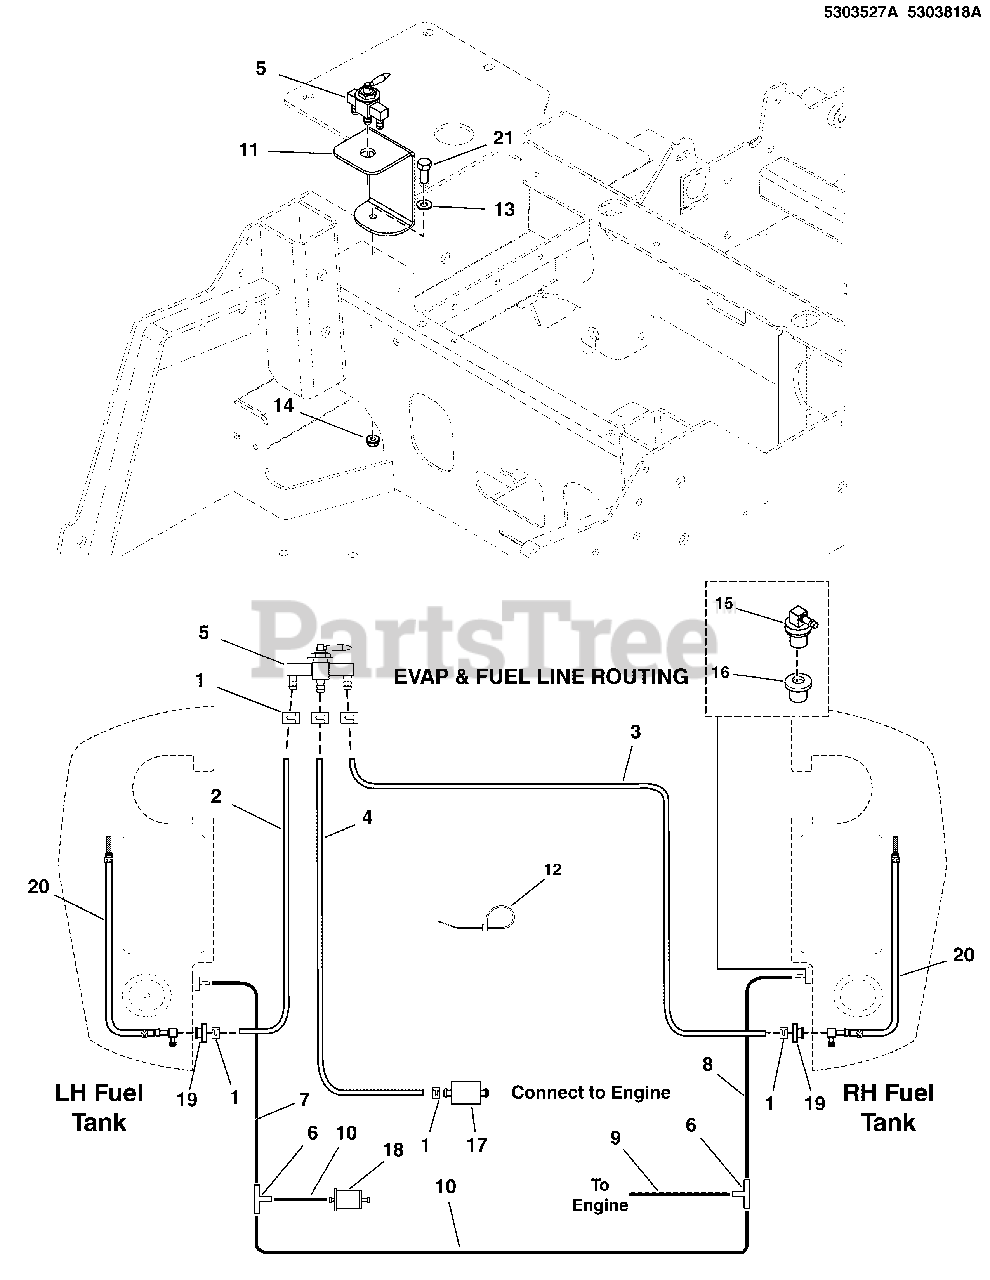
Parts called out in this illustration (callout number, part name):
1	CLAMP, HOSE, EXTERNAL, 1/2 - RED
2	HOSE, 1/4" FUEL, 11.00"
3	HOSE, 1/4" FUEL, 27.00"
4	HOSE, 1/4" FUEL, 19.50"
5	VALVE, FUEL SHUT-OFF, 11772
6	FITTING, 3/16" TEE, BARB TYPE, HDPE
7	HOSE, VAPOR, 5MM ID, 15.50 LG
8	HOSE, VAPOR, 5MM ID, 23.00 LG
9	HOSE, VAPOR, 5MM ID, 13.50 LG
10	HOSE, VAPOR, 5MM ID, 6.00 LG
11	MOUNT, FUEL VALVE, 2100Z - BLK
12	TIE, 6" Self-Locking
13	WASHER, 5/16
14	NUT, Ny Lock Flange, 5/16-18
15	VENT, Remote
16	GROMMET
17	FUEL FILTER (SV)
18	FILTER, Fuel
19	BUSHING
20	PICKUP TUBE ASM, FUEL TANK (SV)
21	CAPSCREW, Hex Head, 5/16-18 x 3/4
